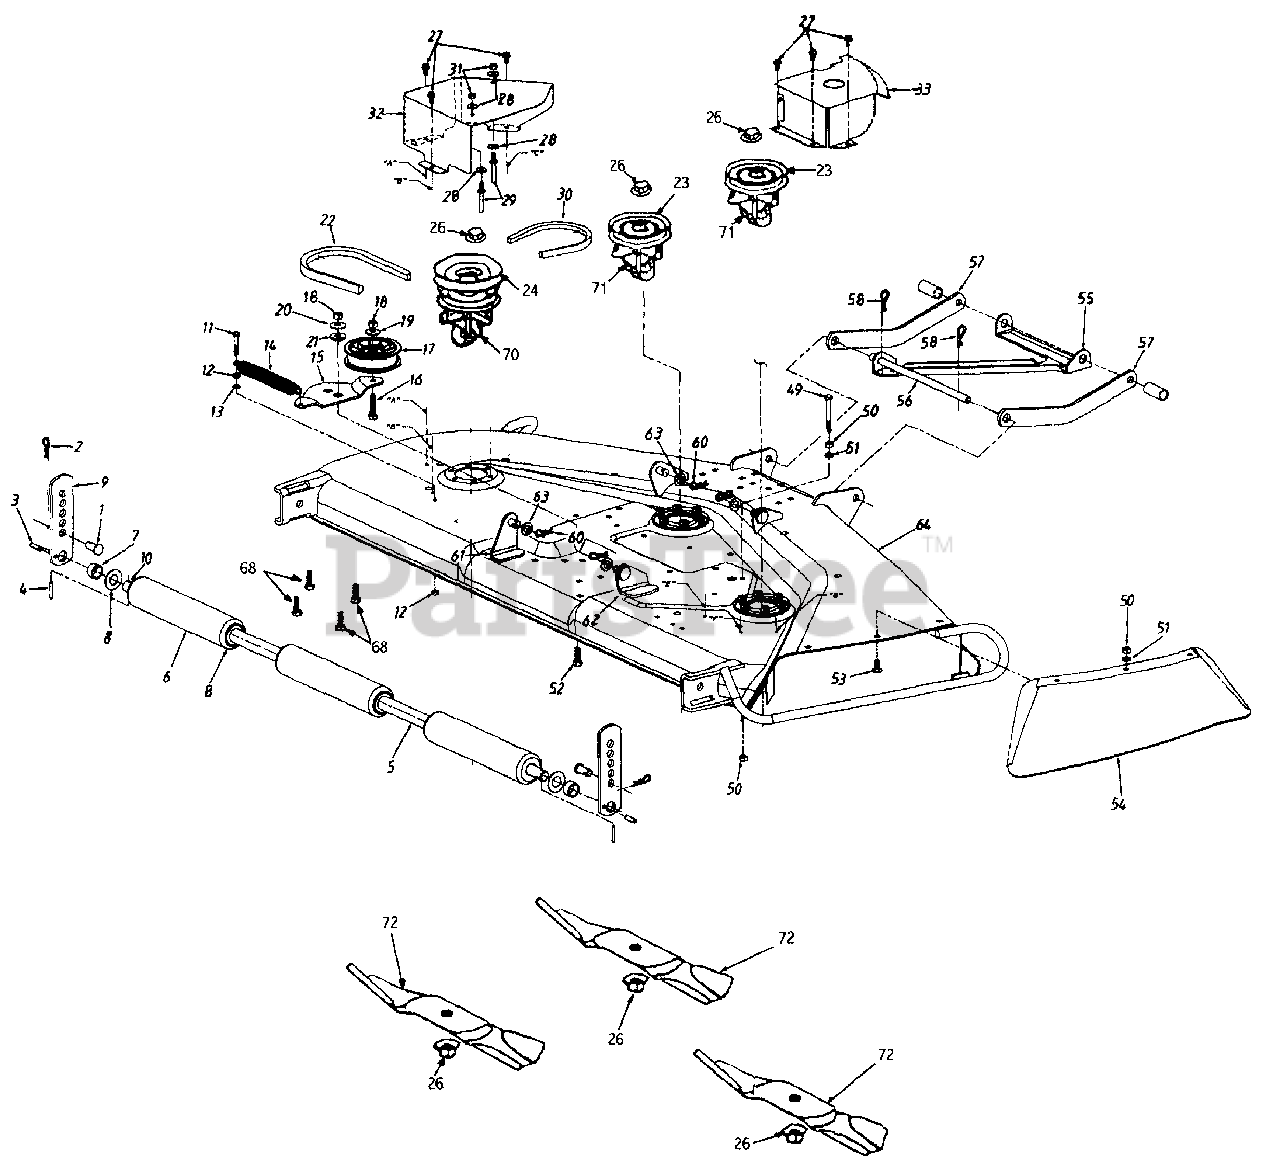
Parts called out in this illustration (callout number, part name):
1	Clevis Pin
2	Hairpin Clip
3	Spring Pin 1/4" x 1" Lg.
4	Spring Pin 3/16" x 1-1/4" Lg.
7	Spacer .75" I.D.
8	Fl-Wash. .76" I.D. x 1.5" O.D.
10	Roller Shaft
11	Hex Bolt 1/4-28 x 1.5" Lg. (Gr. 5)
12	Hex Nut 1/4-28 Thd.
13	L-Wash. 1/4" I.D.
14	Ext. Spring 7.33" Lg.
17	Idler Pulley
18	Hex Nut 3/8-24 Thd.
19	Bell-Wash. 3/8" I.D.
20	Bell-Wash. .39" I.D. x 1.13" O.D.
21	Shld. Spacer .625" I.D.
22	"V"-Belt
23	Deck Pulley
24	Double Deck Pulley
26	Hex Jam Nut 5/8-18 Thd.
27	Hex Wash. Hd. Scr. 1/4-20 x .5" Lg.
28	Bell-Wash. 1/4" I.D.
29	Belt Guard Pin
30	"V"-Belt
31	Hex Nut 1/4-20 Thd.
50	Hex Nut 5/16-18 Thd.
51	L-Wash. 5/16" I.D.
52	Hex Bolt 3/8-24 x 1" Lg.
53	Carr. Bolt 5/16-18 x .75" Lg.
60	Hairpin Clip
63	Fl-Wash. 1/2" I.D. x .93" O.D.
70	Spindle Ass'y. (L.H.)
71	Spindle Ass'y. (R.H. & Center)
72	Blade
12649-0638	GUARD-CHUTE - MTD/TROY-BILT RED (0638)
12649-0648	GUARD-CHUTE - TECH GRAY (0648)
12650-4008	Height Adjuster - WINE RED (4008)
